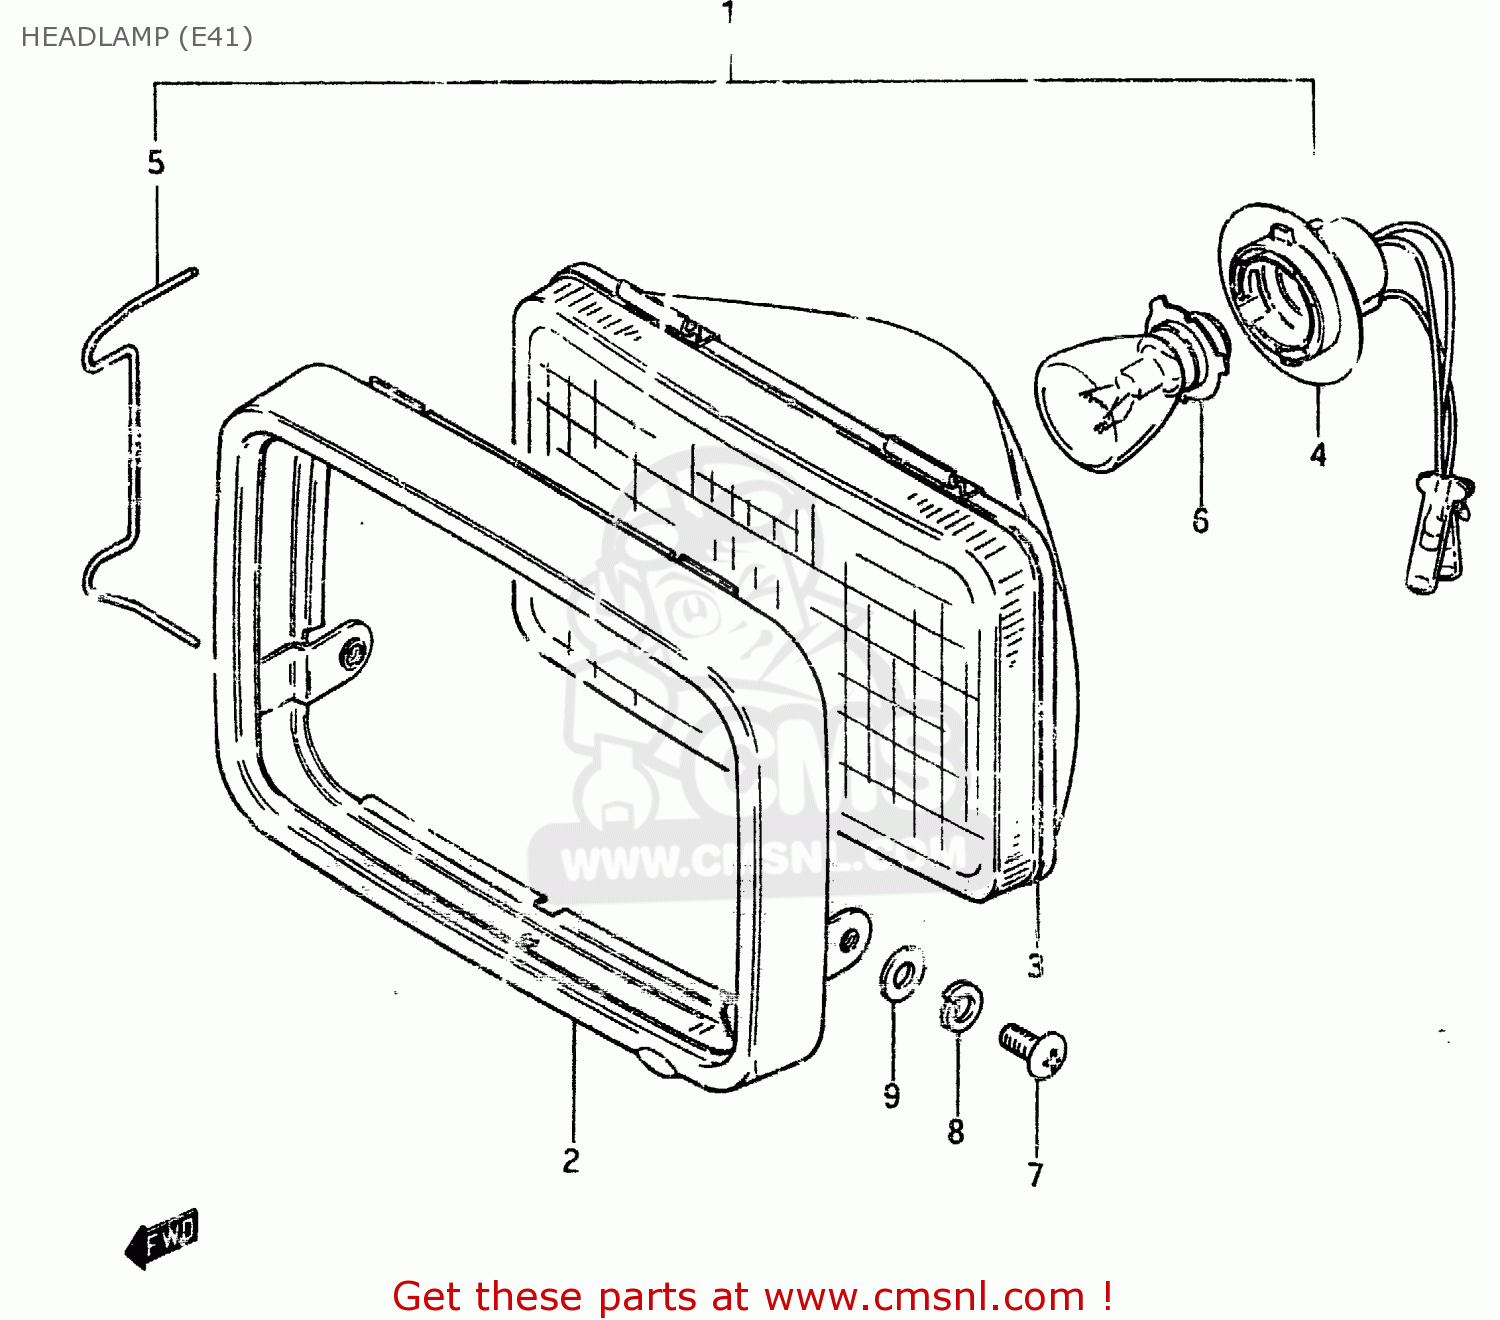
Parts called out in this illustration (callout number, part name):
1	HEADLAMP ASSY
2	RIM
3	UNIT
4	SOCKET
5	SPRING
6	BULB(6V25/25W,STANLEY,A7007)
7	SCREW
8	LOCK WASHER
9	WASHER
